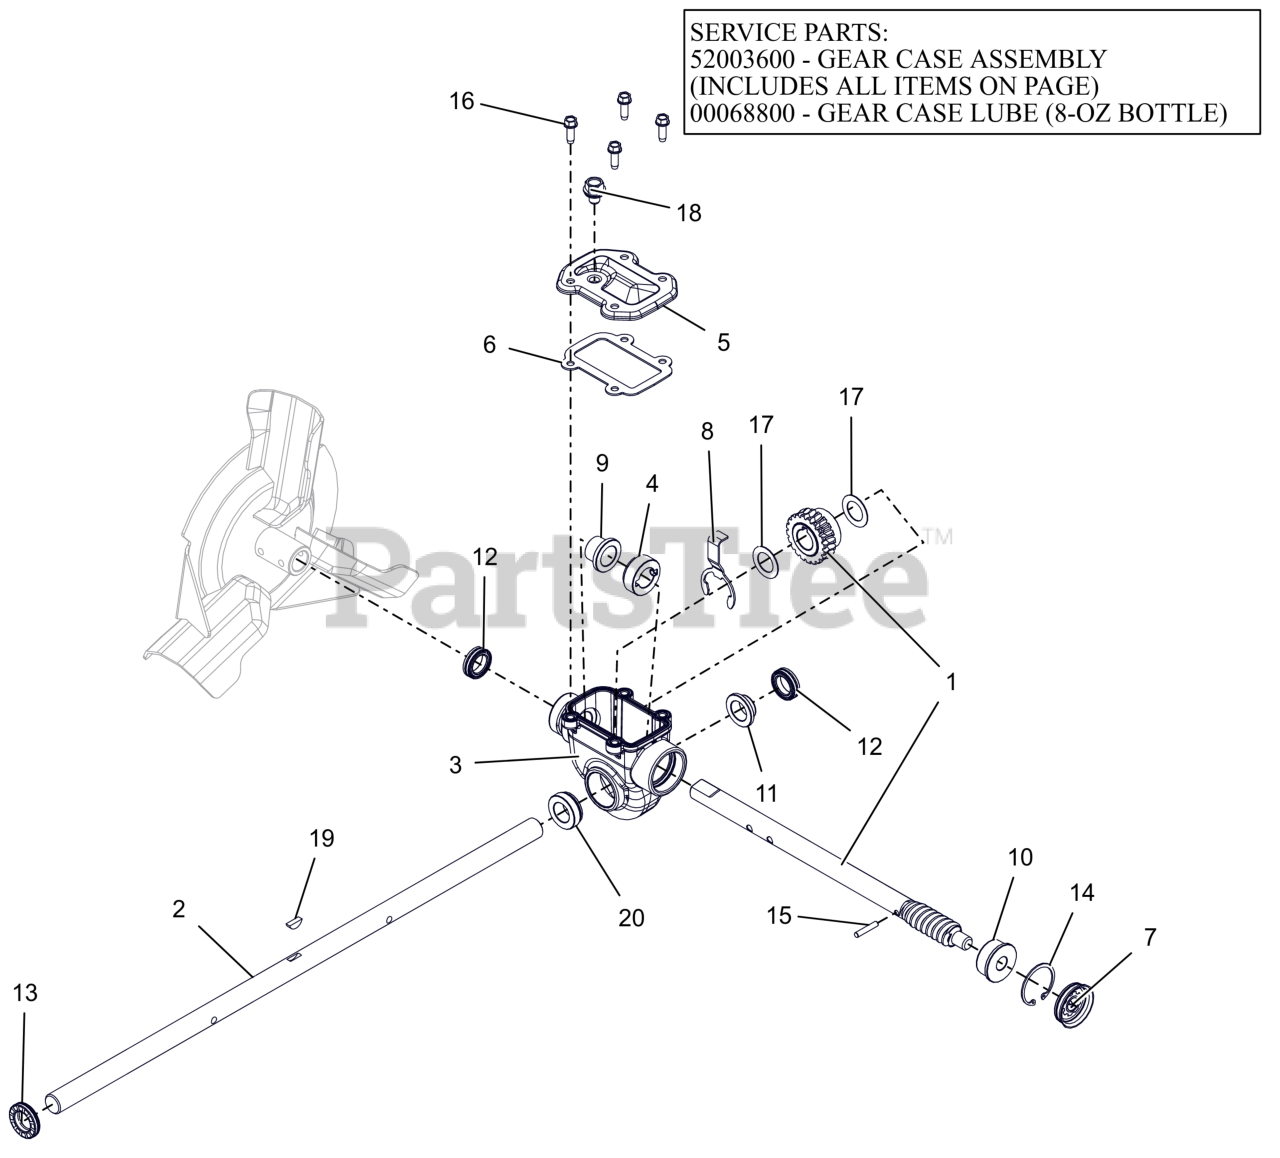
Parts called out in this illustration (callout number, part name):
1	SHAFT AND WORM GEAR ASSEMBLY
2	SHAFT, RAKE - 24" (.750 DIA)
3	GEARCASE, COMPACT ALUMINUM
3	GEAR CASE, 24" ALUM SM TOP-LD
3	ARIENS L3 LUBE, 8 OZ BOTTLE
4	THRUST COLLAR, .75" ID SLIPFIT
5	COVER, TOP - COMPACT
6	GASKET, TOP - COMPACT GEARCASE
7	COVER, GEAR CASE 1.50"
8	BUSHING RETAINER, COMPACT
9	BSHG-FLG .755X.878X.75X1.25
10	BSHG-FLG .503X1.303X.62X1.465
11	BSHG-FLG .755X.878X.424X1.25
12	SEAL-OIL .748X1.125X.312 TBC29
13	SEAL-OIL .748X1.300X.250 TBC29
14	RG-RTNG-INT 1.500X.050
15	PIN-STR .188X1.00 6150
16	SCR,TAP .25-20X.75 HWH TR ZCC
17	WSHR, FLT .760X1.225X.032 ZCC
18	SCR, .380-15X.500 W/SEAL WASHER
19	KEY-WDRF .19X.63 HRD #61
20	BSHG-FLG COMPACT, RIGHT
